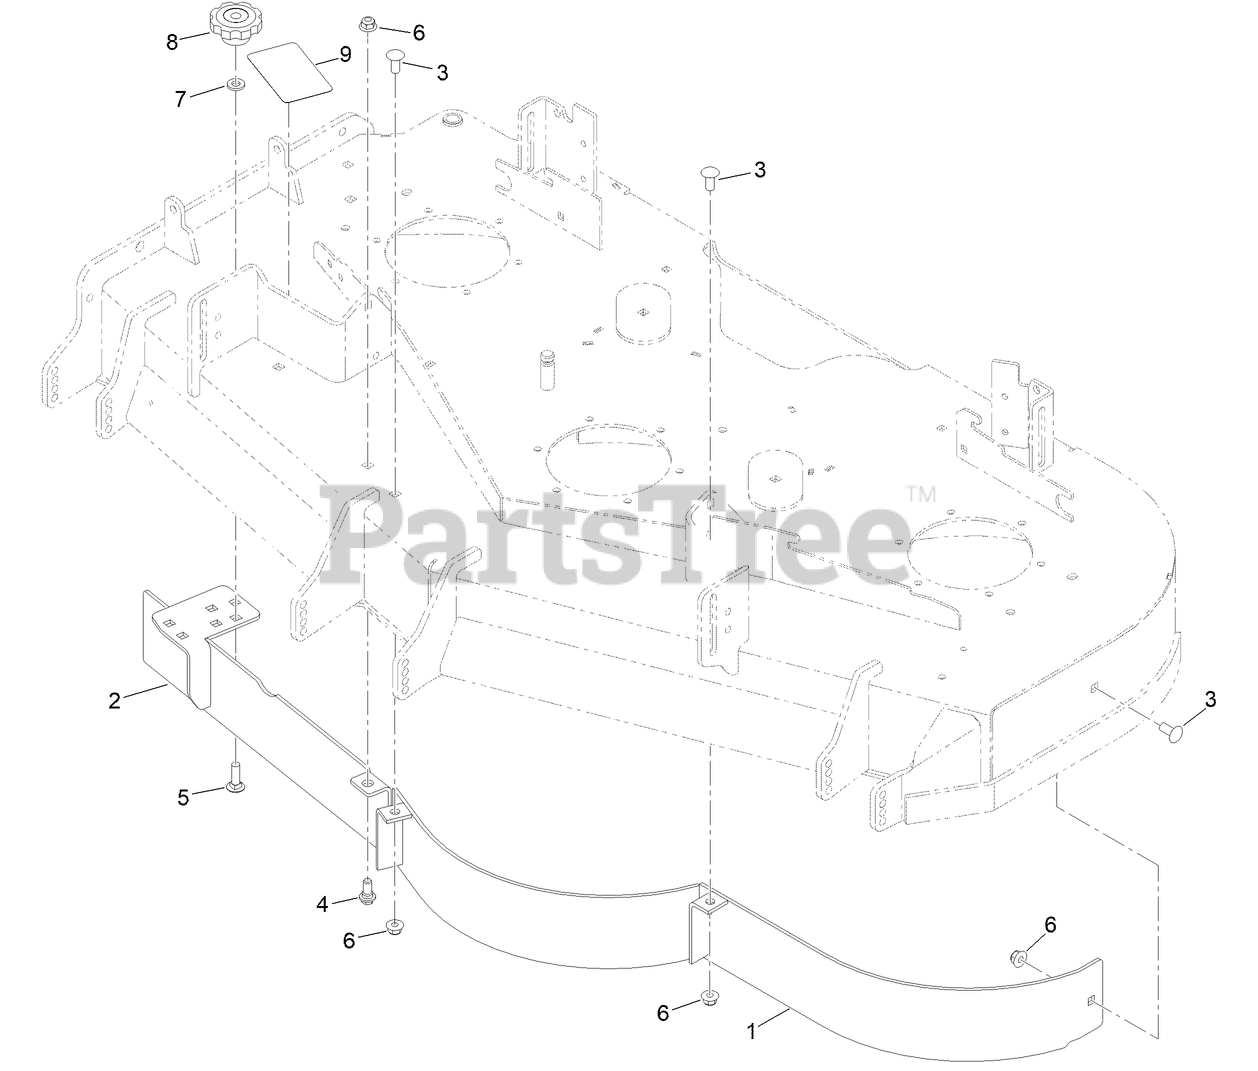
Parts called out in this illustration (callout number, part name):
1	BAFFLE ASM
3	SCREW-CARR
4	BOLT-SHOULDER
5	BOLT-CARR
6	NUT-HF, NI
7	WASHER-HARDENED
9	DECAL-ADJUSTABLE BAFFLE
